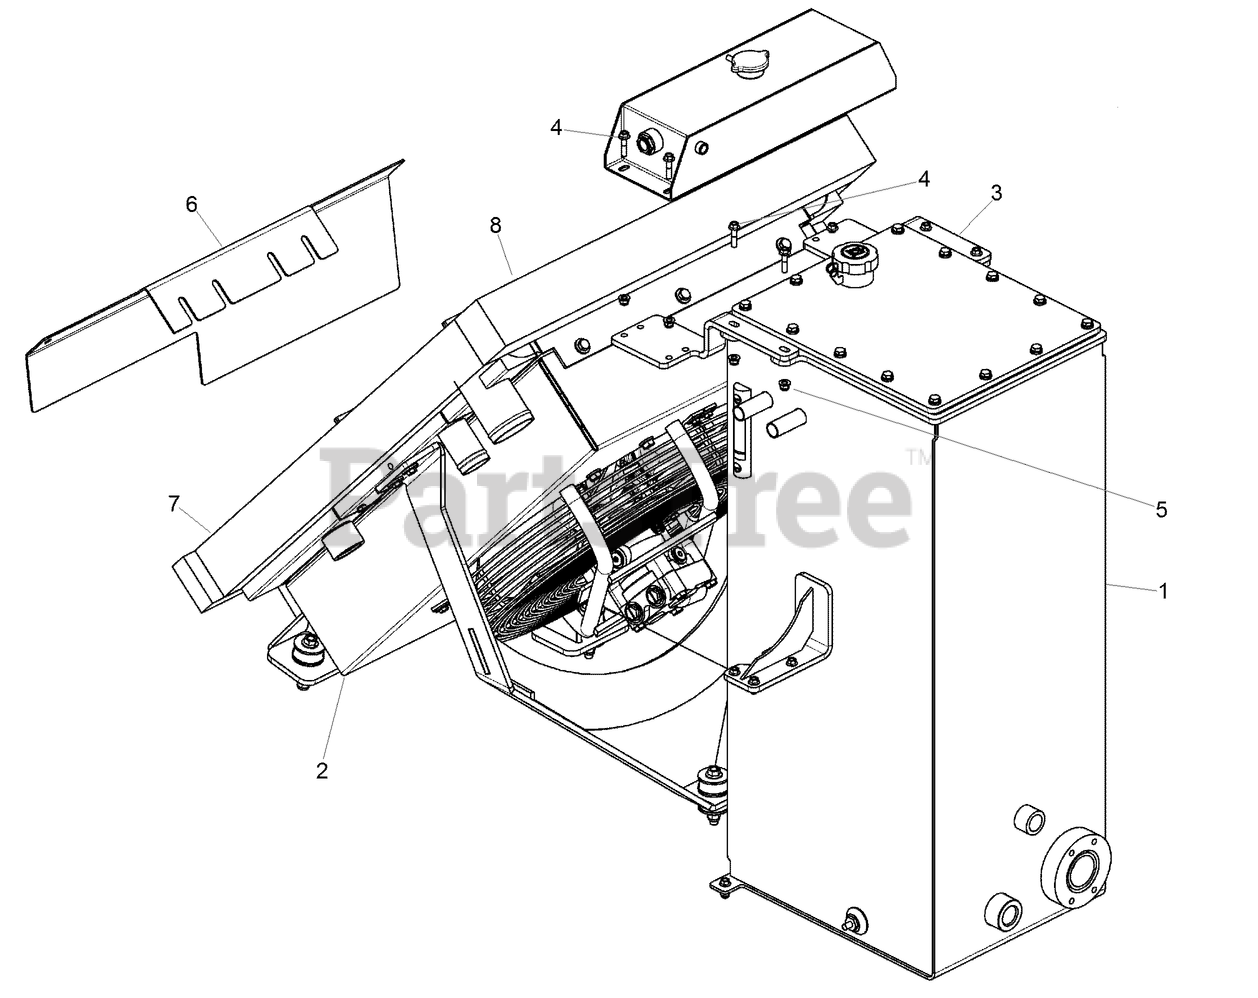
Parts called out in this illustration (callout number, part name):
1	HYD TANK ASM
2	MOUNTING - Cooling Package
3	MOUNT - Filler / Surge Tank
4	SCREW, METRIC FLANGE w/BODY - M8 x 35
5	NUT-TORQUE, PREVAILING
6	SEAL PLATE - Below Cooler
7	FOAM - Polyurethane
8	FOAM-POLYURETHANE
